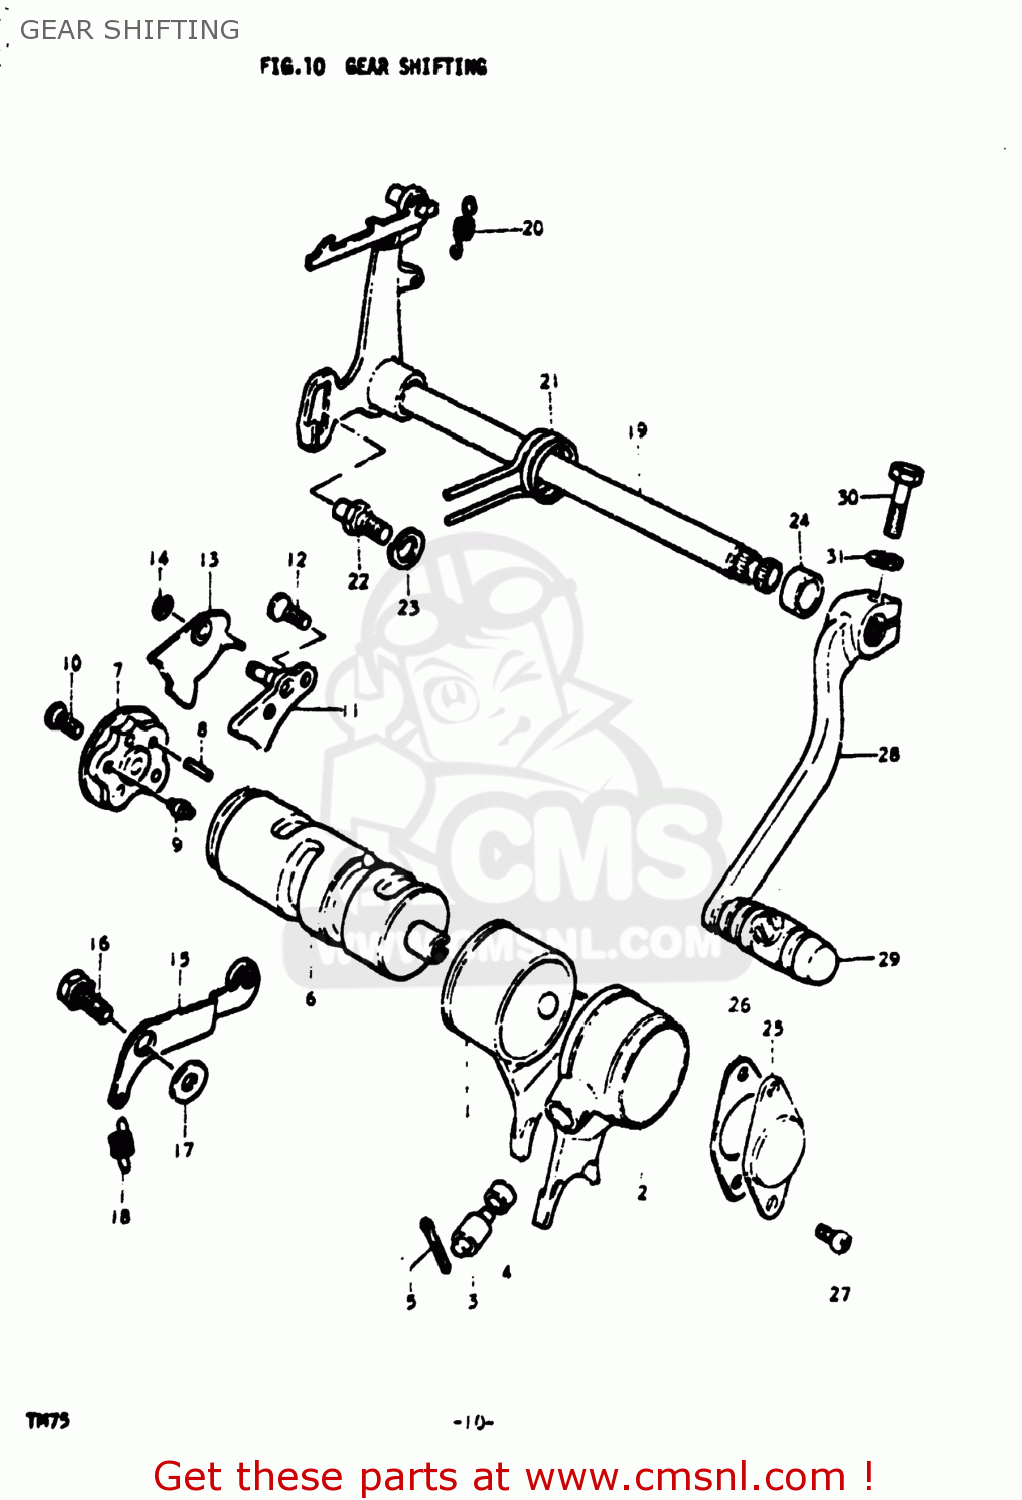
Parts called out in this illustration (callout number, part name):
1	FORK,GEAR SHIFT NO.1
2	FORK,GEAR SHIFT NO.2
3	PIN
4	SPACER
5	PIN 25X20
6	CAM,GEAR SHIFT
7	PLATE,GEAR SHIFT CAM
8	PIN(4X18.5)
9	PIN
10	SCREW
11	GUIDE,GEAR SHIFT CAM
12	SCREW
13	PAWL,GEAR SHIFTING CAM
14	E RING
15	STOPPER,SHIFT CAM
16	BOLT(6X16.1)
17	WASHER(6.5X16X2.3)
18	SPRING
19	SHAFT,GEAR SHIFT
20	SPRING
21	SPRING
22	STOPPER,GEAR SHIFT ARM
23	LOCK WASHER
24	OIL SEAL
26	27
27	SCREW
28	LEVER ASSY,GEAR SHIFT
29	RUBBER,GEAR SHIFT PEDAL
30	BOLT
31	LOCK WASHER
